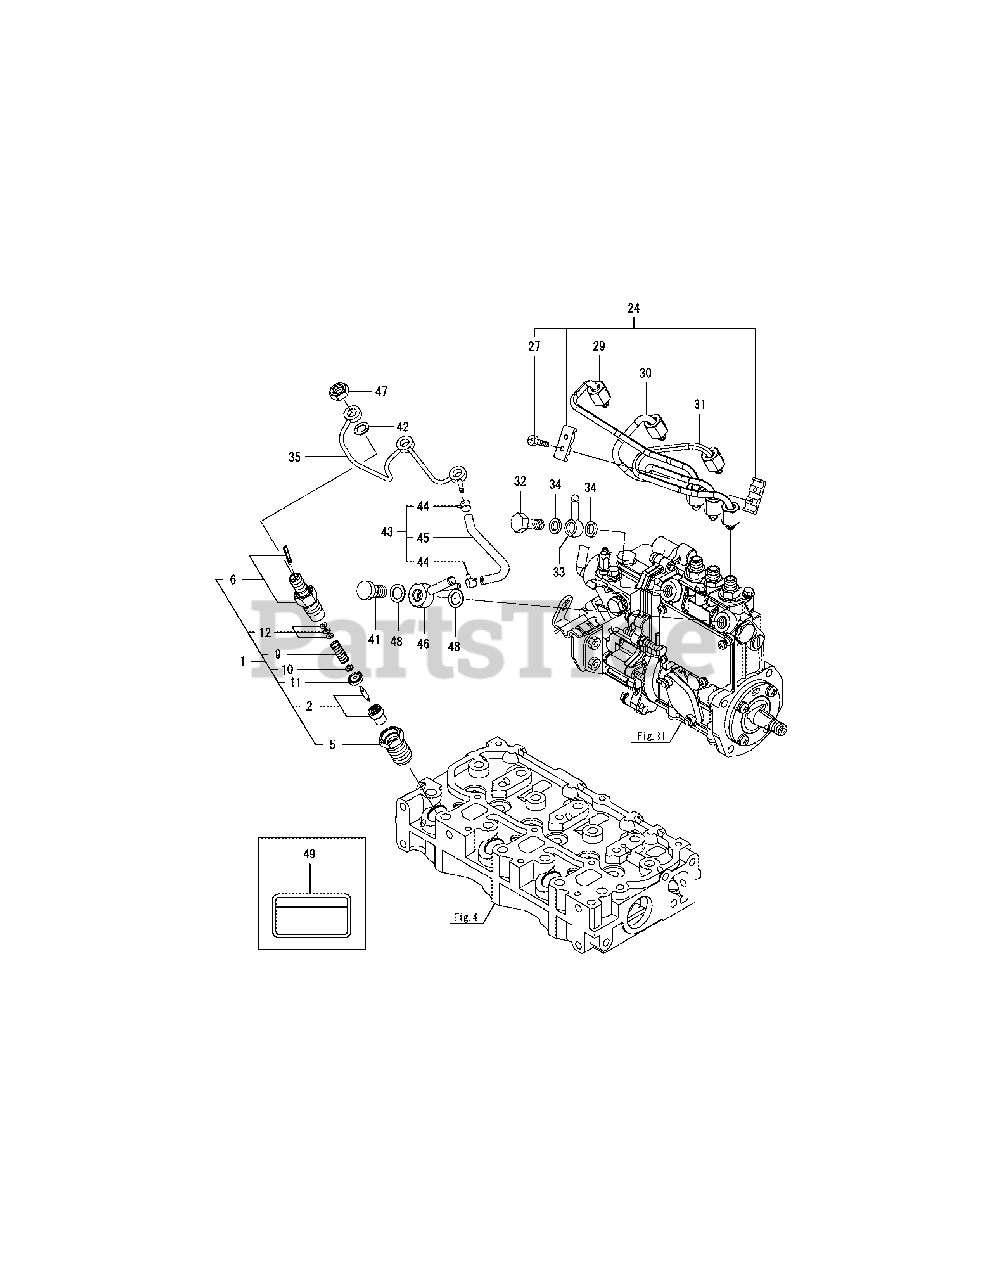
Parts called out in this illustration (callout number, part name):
1	INJECTOR, FUEL
6	HOLDER ASSY, NOZZLE
9	SPRING, NOZZLE
11	SPACER, VALVE STOP
24	RETAINER, PIPE
27	BOLT M4X14,HEX.SCKT.
29	PIPE, FUEL INJECTION
30	PIPE, FUEL INJECTION
31	PIPE, FUEL INJECTION
32	BOLT, PIPE JOINT
33	JOINT, PIPE 12
34	SEAL WASHER 12
35	PIPE ASSY, RETURN
41	BOLT,PIPE JOINT
42	GASKET, RETURN
43	PIPE, FUEL RETURN
45	PIPE, FUEL RETURN
47	NUT, NOZZLE RETURN
48	SEAL WASHER 12
49	LABEL, FUEL OIL
